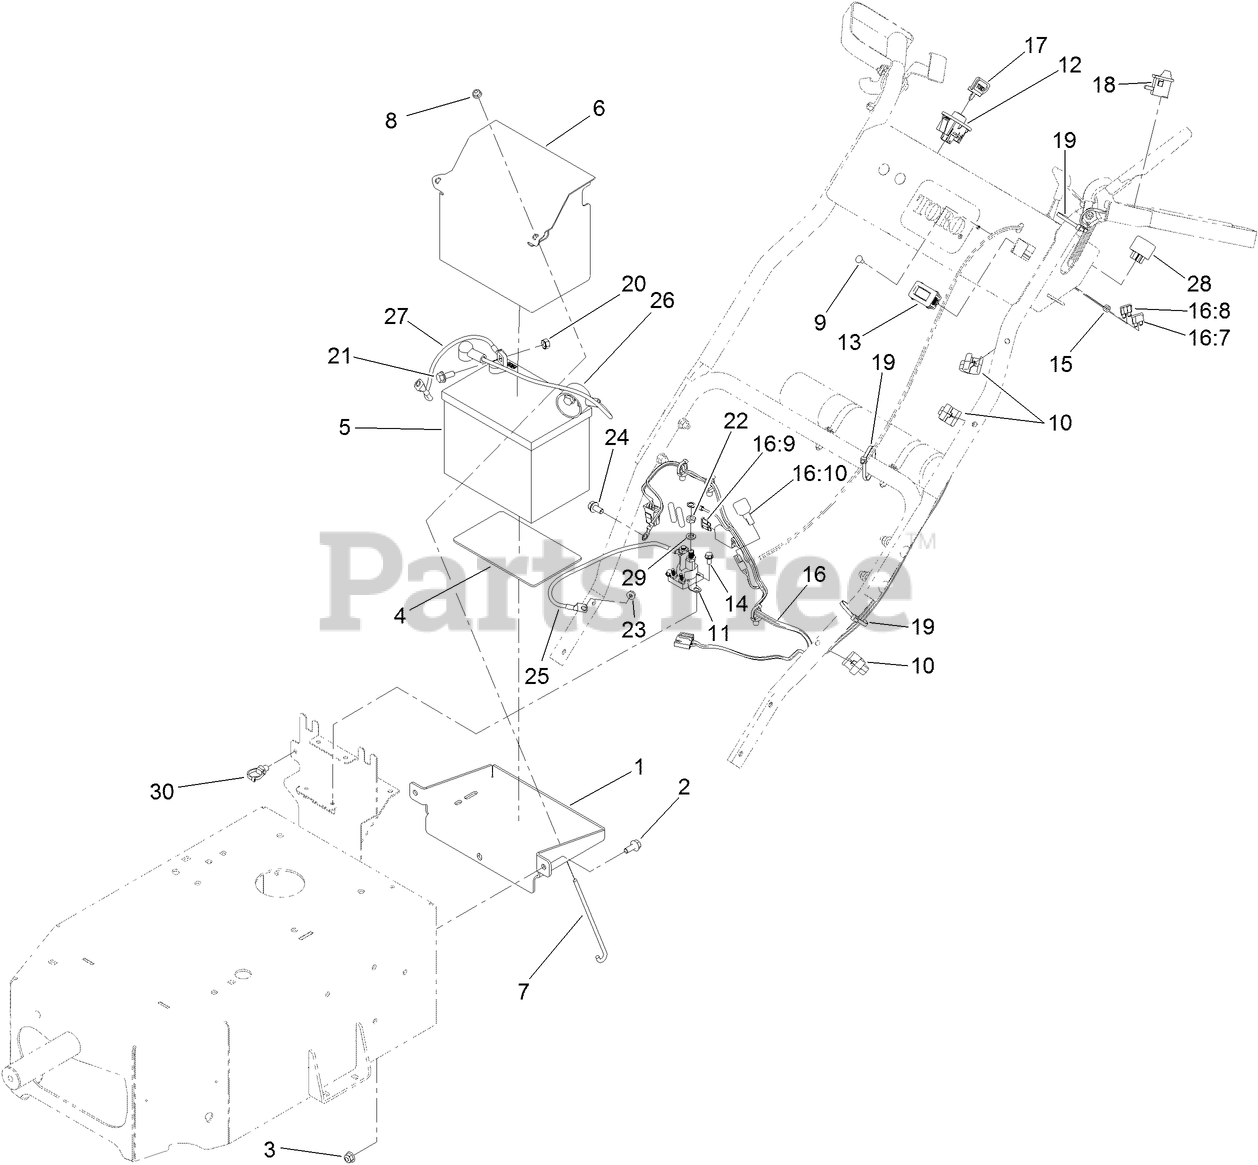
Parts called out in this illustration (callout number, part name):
1	TRAY-BATTERY
2	SCREW-HHF
3	NUT-HF, NI
4	PAD-SKID, ANTI
5	BATTERY
6	TRAY-BATTERY
7	BOLT-HOLDDOWN
8	NUT-HF
9	BOLT-CARR
10	GUIDE-CABLE
11	SOLENOID
12	SWITCH-IGNITION
13	HOURMETER
14	SCREW-HWH
15	NUT-LOCK, NI
16	HARNESS-WIRE
16:7	FUSE-BLADE, 10 AMP
16:8	FUSE-BLADE, 25 AMP
16:9	FUSE-BLADE, 30 AMP
17	KEY-IGNITION
18	SWITCH-PLUNGER
19	TIE-CABLE
20	NUT-KEPS
21	SCREW-HHF
22	NUT-JAM
23	NUT-HF
24	SCREW-HHF
25	CABLE-BATTERY, POSITIVE
26	CABLE-BATTERY, POSITIVE
27	CABLE-BATTERY, NEGATIVE
28	RELAY
29	WASHER-LOCK
30	CLIP-TIE
